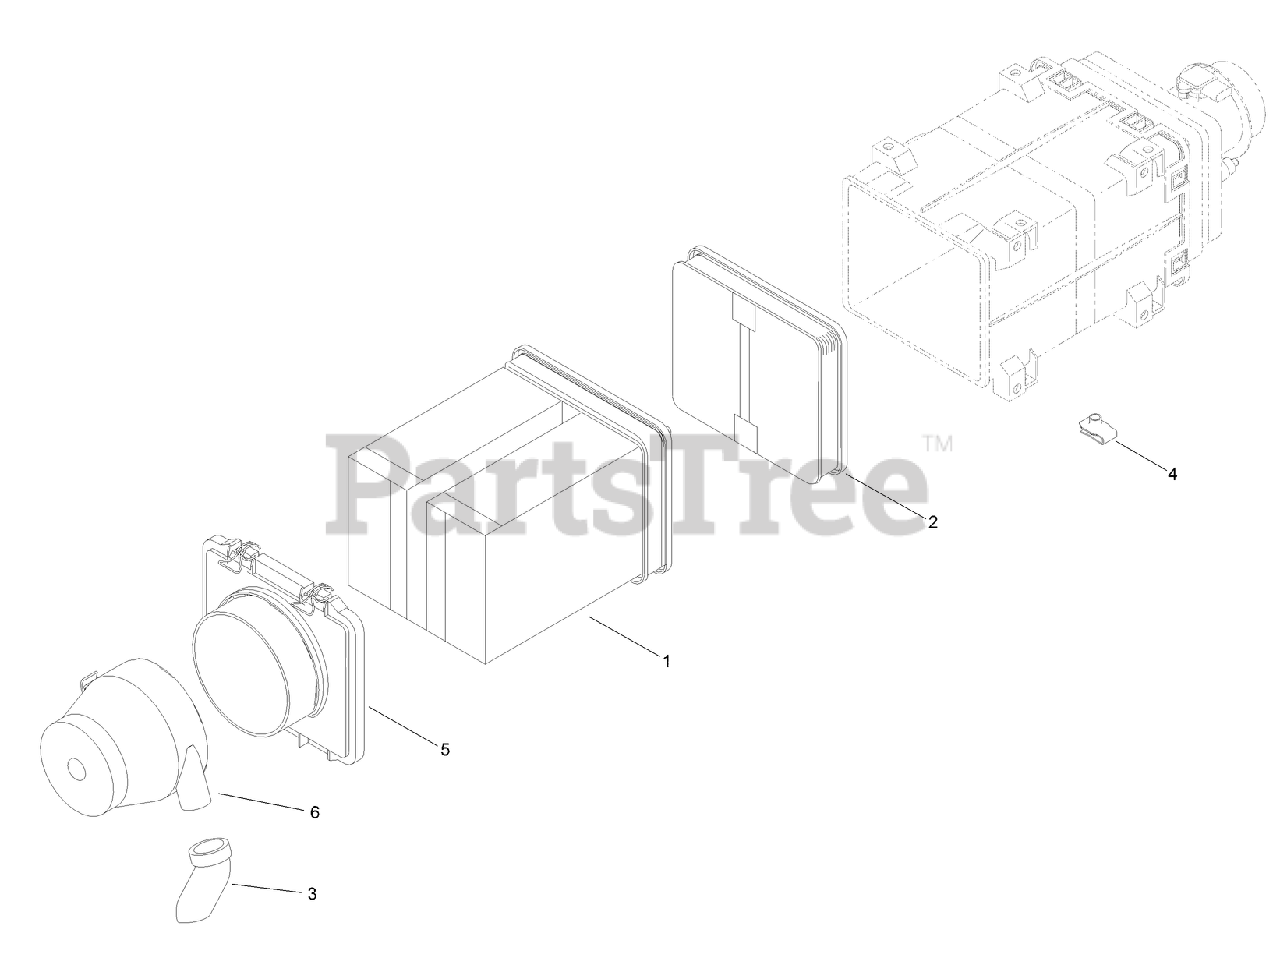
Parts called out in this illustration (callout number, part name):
1	CLEANER-AIR, PRIMARY
2	SECONDARY ELEMENT
3	VALVE-EJECTION, DUST
4	CLIP-MOUNTING, M6
5	COVER-SERVICE, FRONT
6	PRE-CLEANER
